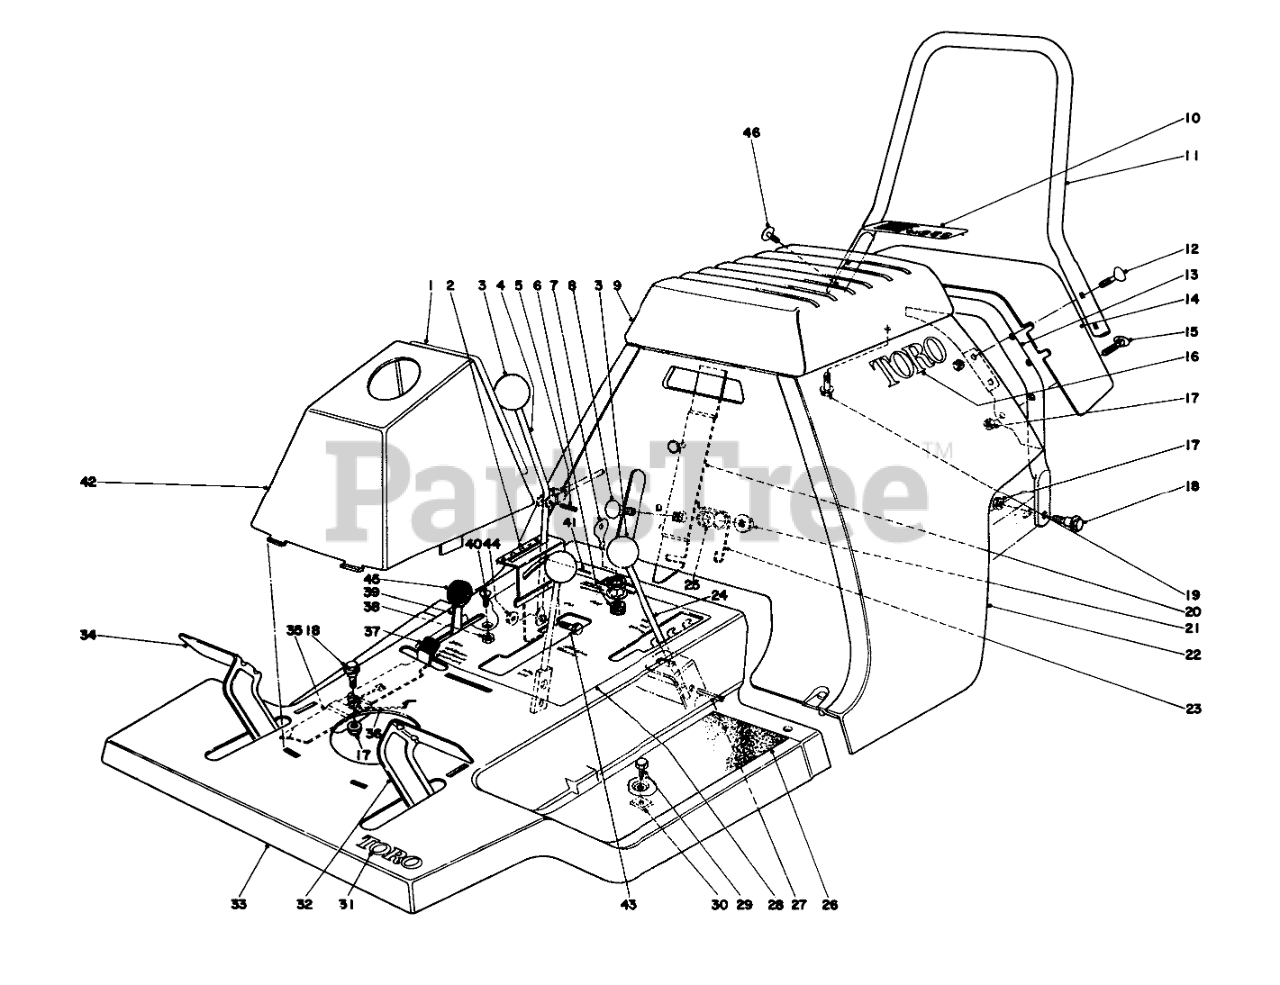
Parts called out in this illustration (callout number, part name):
1	Decal Tower
2	Decal-Shift Pattern
3	KNOB-CONTROL
4	Shift Rod
5	PIN-ROLL
6	ON-OFF SWITCH 21-8-468
7	Key
8	BOLT-CARR
10	Decal-Rear Extension (Model 56020 only)
11	Handle Upper
12	BOLT-CARR
13	Handle Lower
14	Extension-Rear Body
15	HANDLE SCREW
16	Decal
17	NUT-LOCK, CONE
18	SCREW-SHOULDER
19	SCREW-HHF
20	Handle Latch
21	NUT-HF
22	Rear Body
23	Latch Return Spring
24	Height of Cut Lever
25	Spacer
26	Foot Tread L.H.
27	PIN-ROLL
28	Decal-Panel Control (Model 56020 only)
29	SCREW-HH
30	NUT-TINNERMAN
31	DECAL
32	Clutch Pedal
33	Body-Front
34	Brake Pedal
35	Parking Brake
36	SPRING-PARKING BRAKE
37	TIP-PARKING BRAKE
38	NUT-LOCK, SIDE
39	Throttle Control
40	10-24X 1/2 PHILLIPS SCR
41	PIN-SPRING
42	Tower
43	SCREW-SHOULDER
44	NUT-LOCK, CONE
46	SCREW-HH
